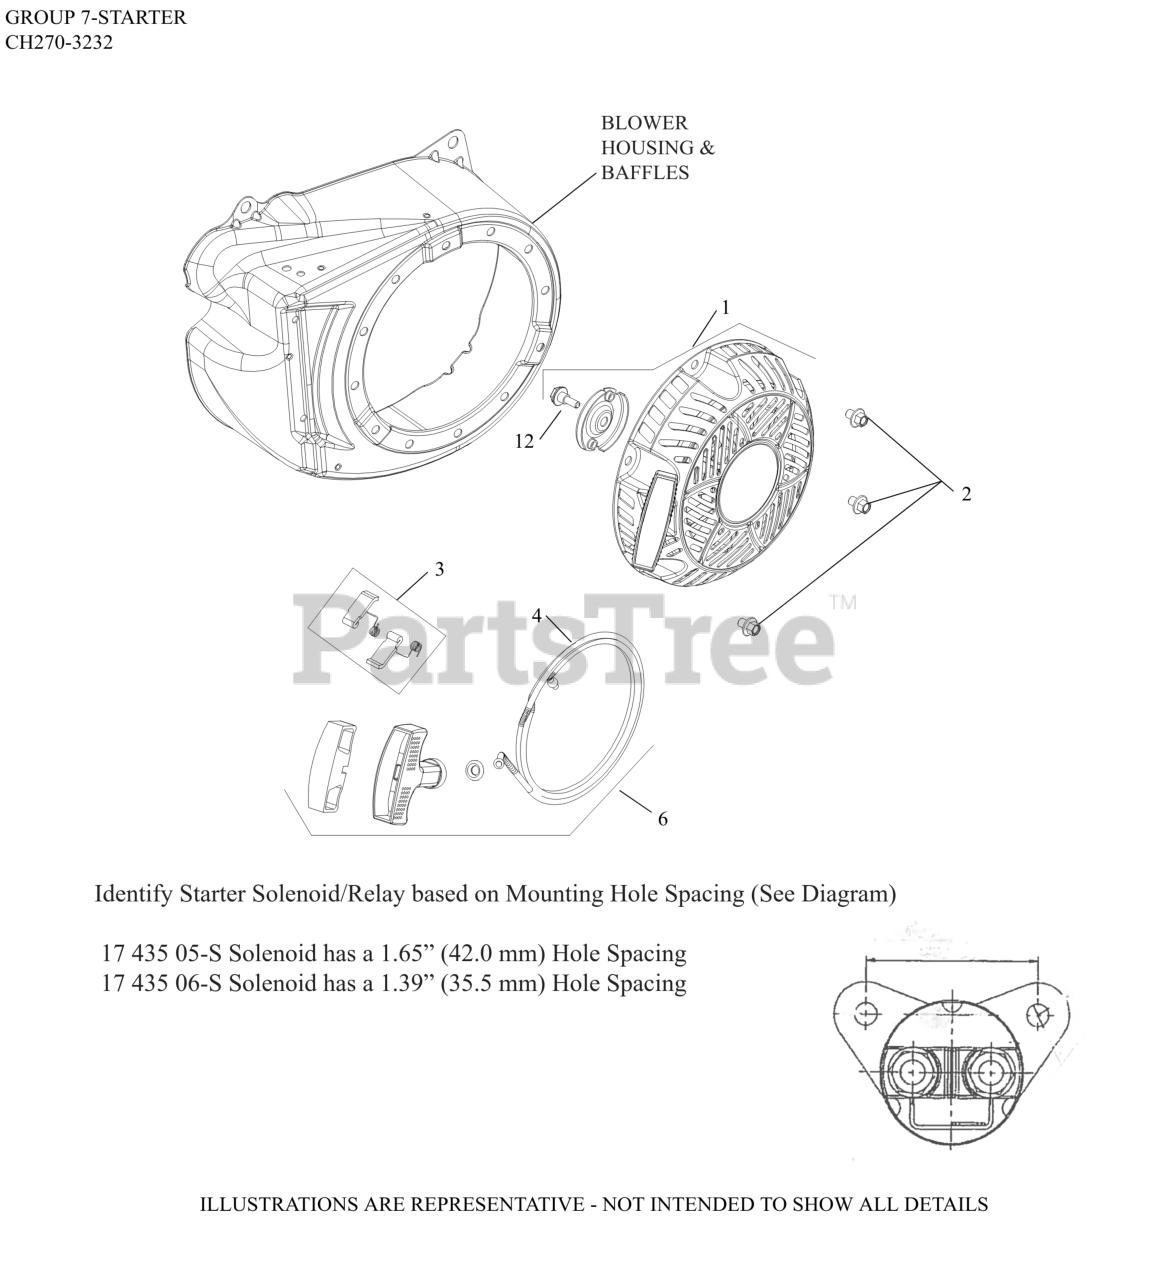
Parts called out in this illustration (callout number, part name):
1	STARTER ASSEMBLY, RETRACTABLE
2	SCREW, M6 X 8 HEX FLANGE HEAD
3	KIT, PAWL REPAIR
4	ROPE, STARTING
6	KIT, STARTER ROPE W/HANDLE
6	KIT, ROPE & HANDLE
12	SCREW, SHOULDER (M5)
